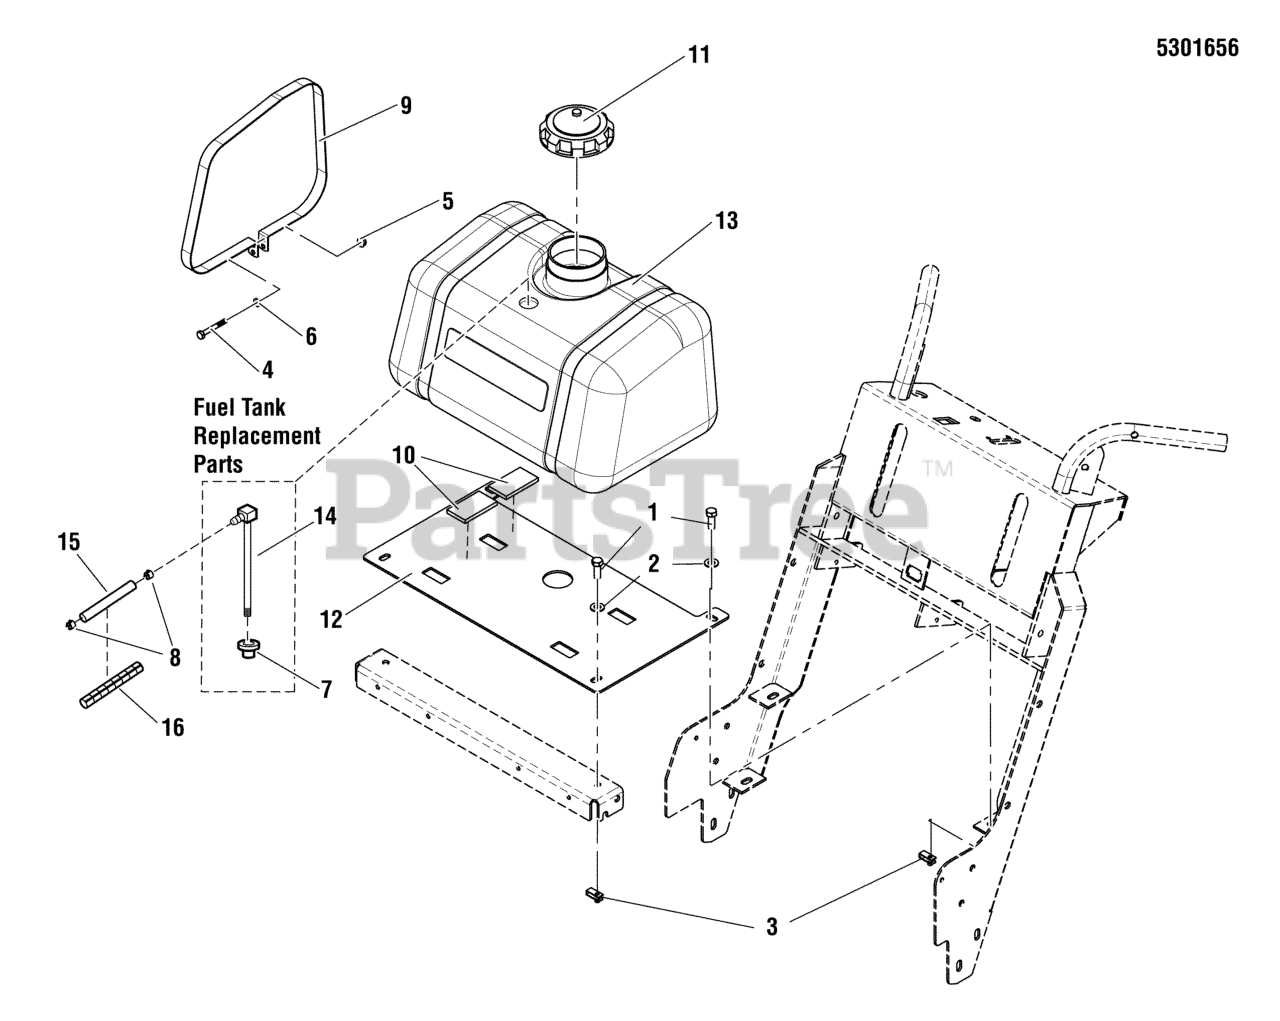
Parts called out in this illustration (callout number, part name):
1	BOLT, 3/8-16 X 1" GD5 CZ
2	WASHER, 3/8 SAE
3	BODY CLIP, 3/8-16 X .688" DEEP
4	BOLT, 1/4-20 X 1-3/4", GD5
5	NUT, 1/4-20 HEX NYLOCK FLANGE
6	WASHER, 1/4 SAE
7	BUSHING-FUEL TANK RED RUBBER
8	CLAMP, HOSE, EXTERNAL, 1/2 - RED
9	STRAP, FUEL TANK
10	PAD, RUBBER MOUNT, 1/4 MAT
11	CAP, GASOLINE, VENTED
12	PLATE, FUEL TANK MOUNT - RED
13	TANK, FUEL, WALK BEHIND
14	PICKUP TUBE ASM, FUEL TANK, 8.0" (SV)
15	HOSE, 1/4" FUEL, 19.00"
16	WIRE LOOM, 1/2" ID, 17" LONG
